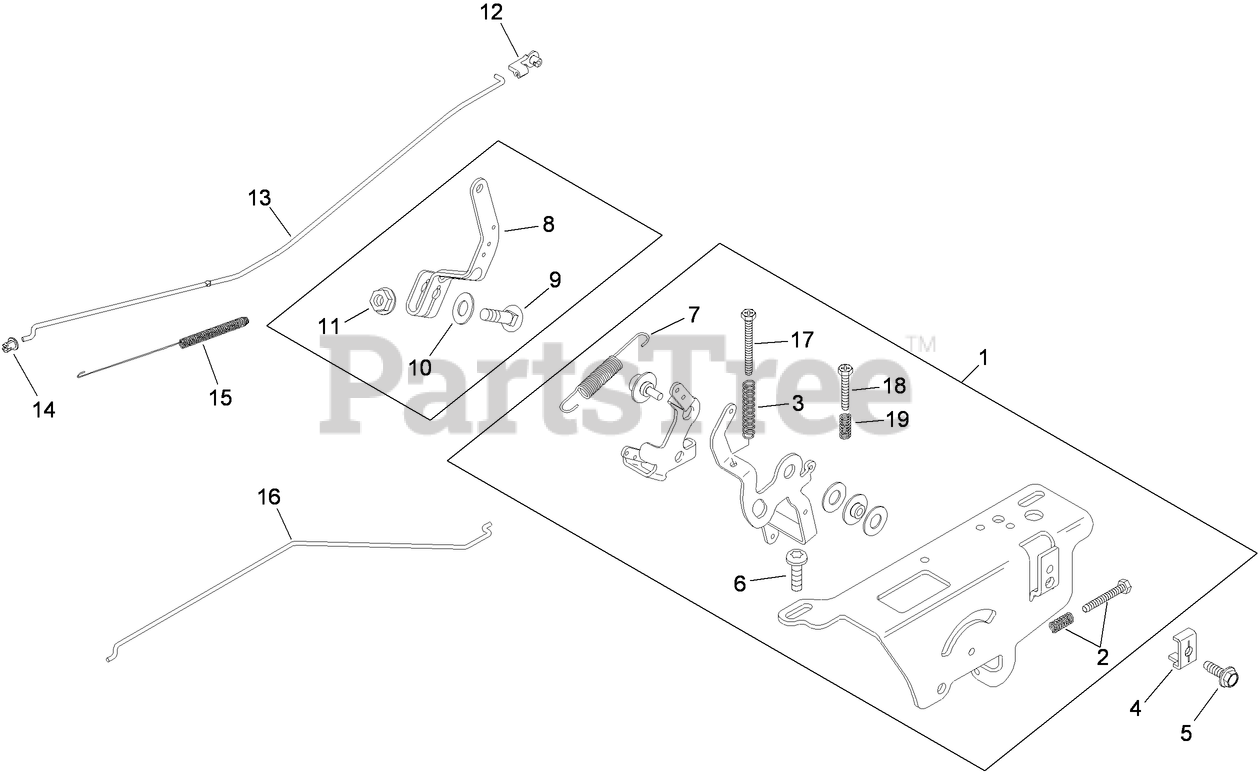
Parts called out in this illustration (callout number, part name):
1	SPEED CONTROL ASM (INCLUDES REF 2, 3, 6 [QTY 1], 7, 17, 18, 19)
2	IDLE ADJUSTING SCREW AND SPRING KIT
3	SPRING-CONTROL, SPEED (LONG)
4	CLAMP-CABLE
5	SCREW-FLANGE, THREAD FORMING (M5X0.8X16)
6	Screw-Socket, 6 Lobed (Thread Forming, M6x1.0x20)
7	Spring-Governor
8	GOVERNOR LEVER ASM (INCLUDES REF 12-15)
9	Bolt-Square Neck, Round Head (1/4-20x1)
10	Washer-Lock, Internal Tooth (1/4)
11	Nut-Flange, Hex (1/4-20)
12	BUSHING-RETAINING, LINKAGE
13	LINKAGE-THROTTLE
14	BUSHING-LINKAGE, THROTTLE
15	Spring-Linkage
16	Linkage-Choke (Single Wire)
17	SCREW-PHL THD FRM (M4X0.7X38)
18	Screw-Thread Forming (M4x0.7x25)
19	Spring-Control, Speed
